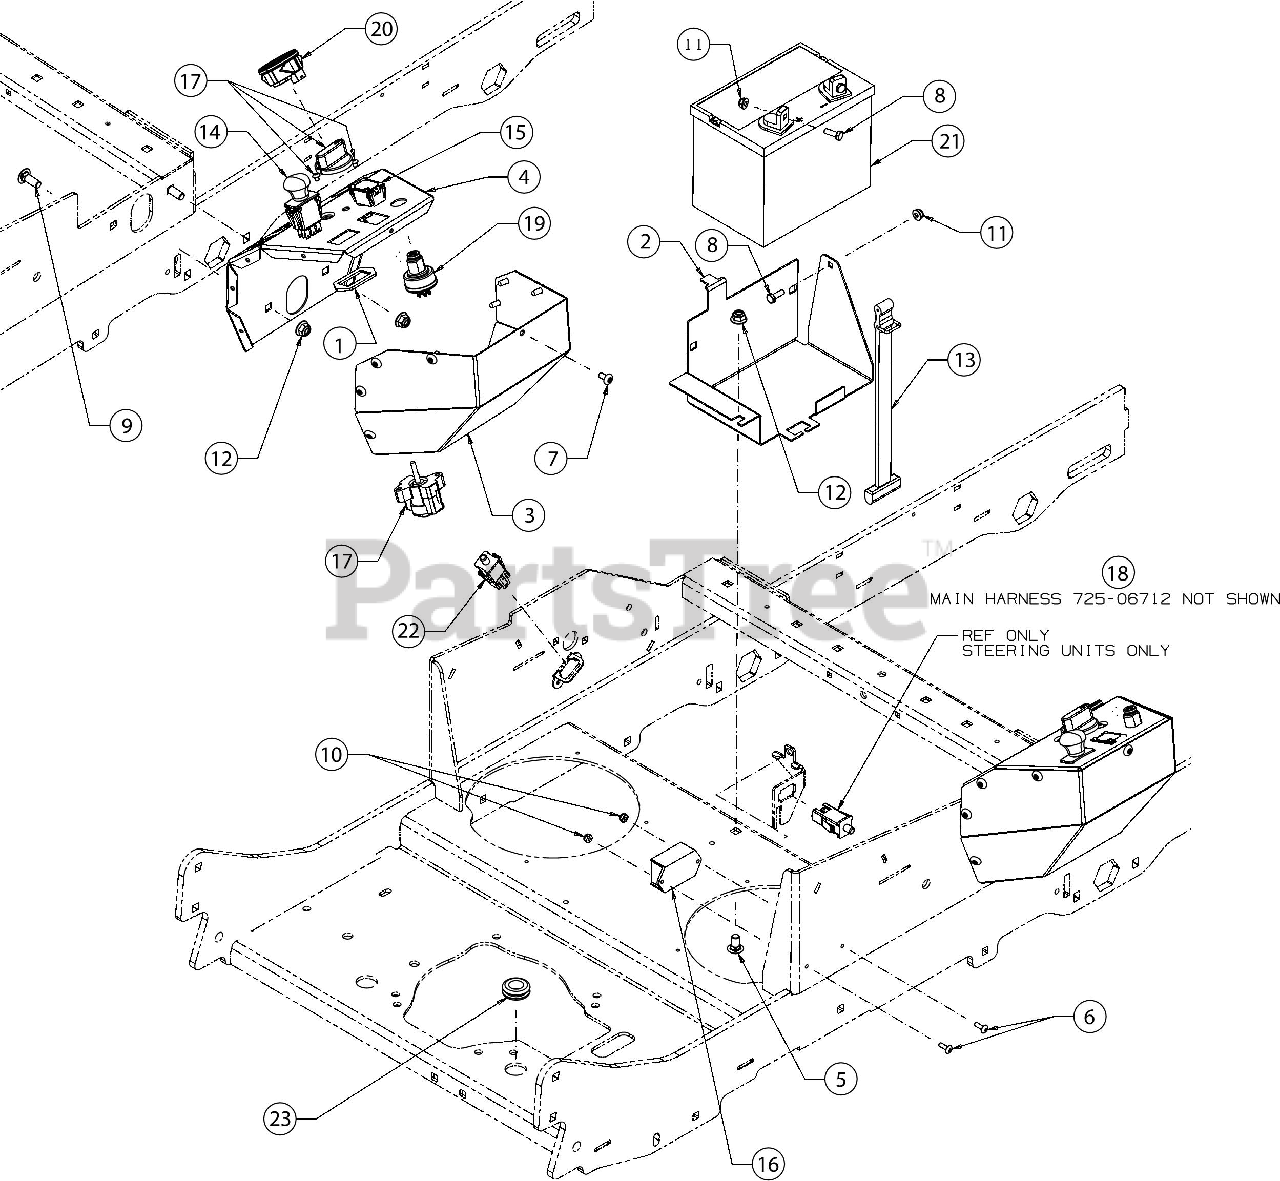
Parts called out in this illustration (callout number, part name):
1	BRACKET-PTO SWITCH
2	BATTERY MOUNTING BRACKET
3	CONTROL POD COVER (RH)
4	CONTROL POD RH
5	CARRIAGE BOLT 3/8-16 x .750 GR5
6	SCREW #10-24 x .62
7	SCREW 1/4-14 x .625
8	SCREW 1/4-20X.75 GR5
9	CARRIAGE BOLT 3/8-16 x 1.00 GR5
11	FLANGE LOCK NUT
13	BATTERY RETAINER STRAP
14	ELECTRIC PTO SWITCH
15	HOUR METER
16	CONTROL PANEL
17	THROTTLE SWITCH
18	WIRE HARNESS ASSEMBLY KOH/EFI
19	KEY SWITCH (3 POSITION)
20	DUAL FUEL GAUGE
22	PLUNGER SWITCH
23	RUBBER GROMMET
